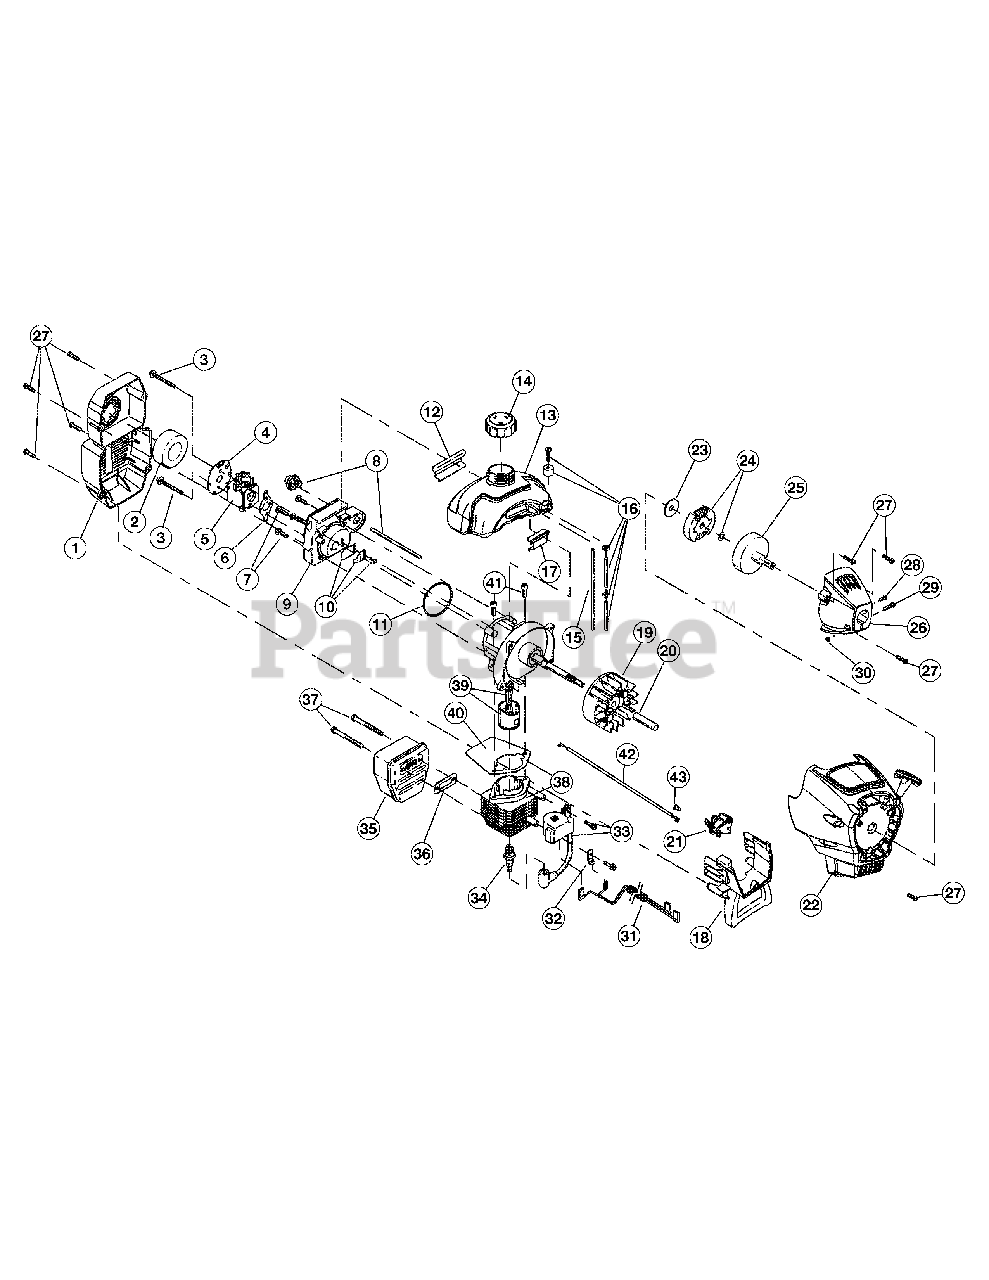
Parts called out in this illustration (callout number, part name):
1	Air Cleaner Assembly (Incl. Ref No. 2 & 27)
2	Air Cleaner Filter
3	Carburetor Mounting Screw Assembly
4	Choke Plate
5	Carburetor Assembly (Incl. Ref No. 6 & 16)
6	Carburetor Gasket
7	Carb Mount Screw
8	Primer and Hose Assembly
9	Carb Mount Assembly (Incl. Ref No. 7, 10 & 11)
10	Reed Assembly
11	Carburetor Mount Gasket
12	Rear Mounting Pad
13	Fuel Tank Assembly (Incl. Ref No. 14-16)
14	Fuel Cap Assembly
15	Fuel Return Line
16	Fuel Line Assembly
17	Front Mounting Pad
18	Shroud Extension & Stand (Incl. Ref No. 27)
19	Flywheel Assembly
21	ACL Lever Assembly
22	Starter Housing Assembly (Incl. Ref No. 21, 42 & 43)
23	Clutch Washer
24	Clutch Rotor Assembly
25	Clutch Drum Assembly
26	Clutch Cover Assembly (Incl. Ref No. 27-30)
27	Cover Screw
28	Anti-Rotation Screw
29	Clamping Screw
30	Clamping Nut
31	Wire Leads and Sleeve
32	Ground Tab
33	Module Assembly (Incl. Ref No. 32)
34	Spark Plug
35	Muffler Assembly (Incl. Ref No. 36 & 37)
36	Exhaust Gasket
37	Muffler Mounting Bolt Assembly
38	Cylinder Assembly (Incl. Ref No. 40 & 41)
39	Piston and Rod Assembly
40	Cylinder Gasket
41	Cylinder Bolt
42	ACL Throttle Cable
43	ACL Screw
